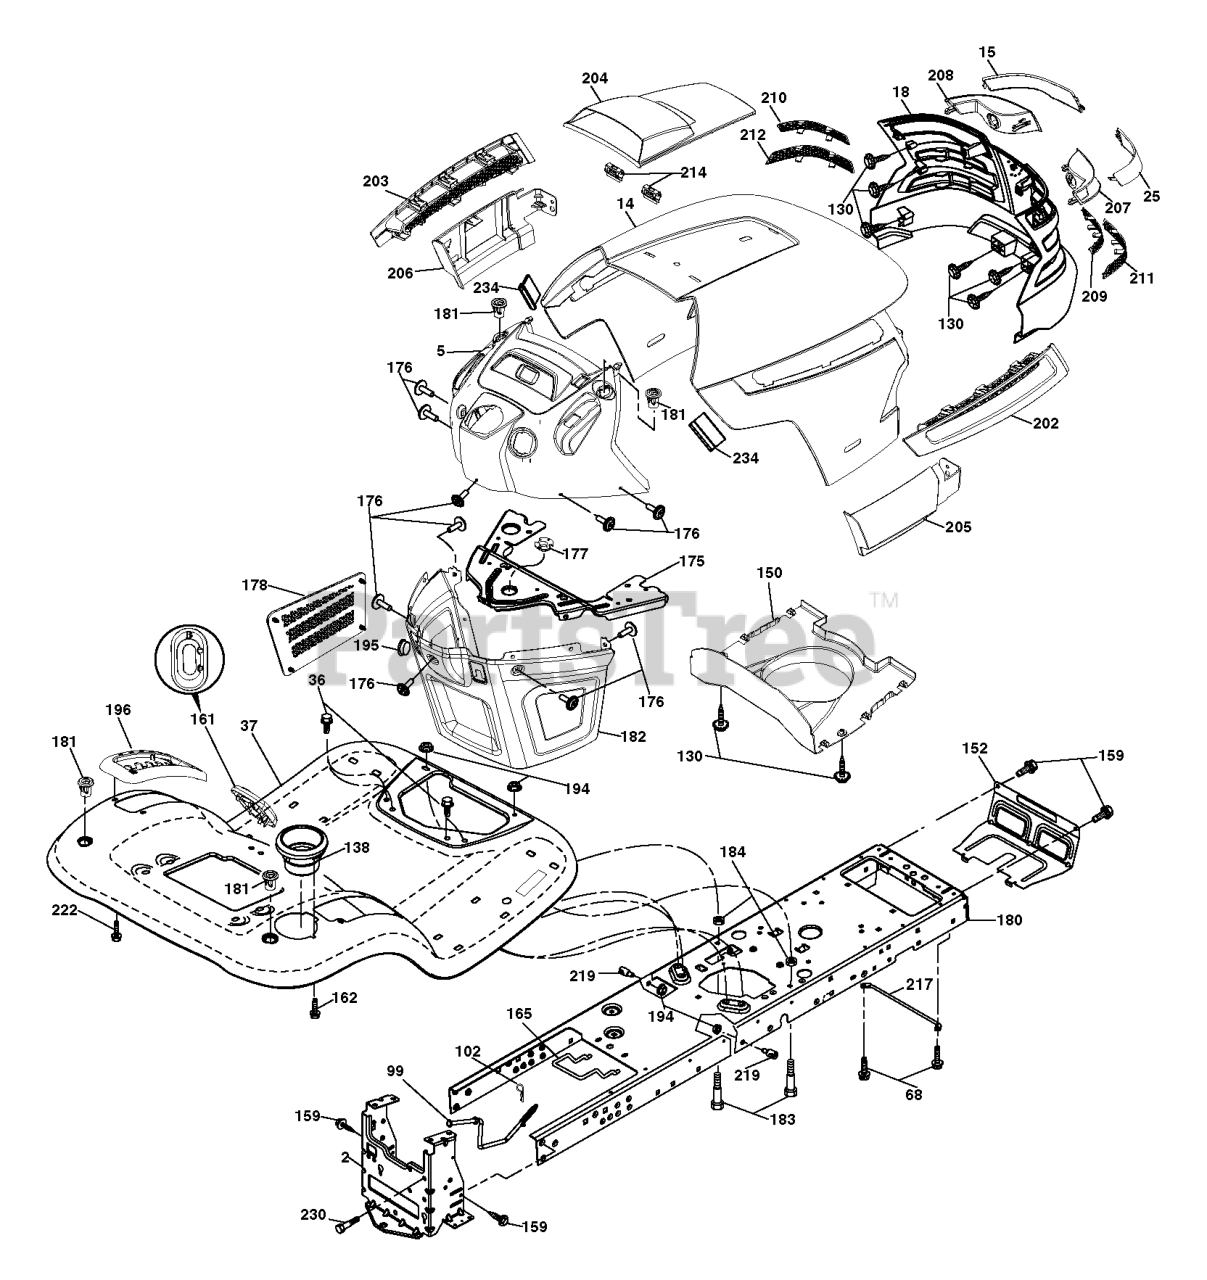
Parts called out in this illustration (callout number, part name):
2	DRAWBAR.1PC.NSTL
5	DASH.HUSQ.UPR.ELE.SVMD
14	HOOD.PNT.HUSQVARNA.GT.
15	LENS.LH.TEX.GT.HUSQ.CL
18	GRILLE.ASM.TX.GT.HUSQ
25	LENS.RH.TEX.GT.HUSQ.CL
36	SCREW 5/16"
68	Screw Thdrol 5/16-18 x 1/2
99	ROD ASM BYPASS
102	RETAINER M
130	SCREW
138	CUPHOLDER.TL.TEX.418
150	AIR.DUCT.TEXGT.HUSQ.SV
152	SHIELD.BROWNING/DEBRIS
159	SCREW, 3/8-16X3/4
161	RP WINDOW.FUEL.LT.TEX.GREY
162	SCREW.HI-LO.CONSOLE
165	SUPPORT.TANK.REAR.WIRE
175	PLATE.CROSSMEMBER.HUSQ
176	SCREW.#10-24X5/8.RN.QU
177	BUSHING, STEERING
178	CARGO.ASM.NET.TXGT.W/C
180	CHASSIS.STAMPING.LT/GT
181	BUSHING.MNT.FEND.CRGO.
182	DASH.LOWER.COMMON.12V.
183	BOLT.5/16-18X1-1/4 FULL.THREAD
184	SPACER.FENDER
194	NUT LOCK HEX FLANGE 5/16-18
195	PLUG.HOLE.DASH.LOWER.12V.BLK
196	CONSOLE.ASM.DECK.LIFT.
202	VENT.SIDE.HOOD.HUSQ.RH.GREY
203	VENT.SIDE.HOOD.HUSQ.LH.GRAY
204	VENT.TOP.HOOD.HUSQVARN
205	SKIRT.HOOD.SIDE.HUSQ.RH.GREY
206	SKIRT.HOOD.SIDE.HUSQ.LH.GREY
207	BEZEL.RH.TEX.GT.HUSQ
208	BEZEL.LH.TEX.GT.HUSQ
209	INSERT.HEX.GRILL.HUSQ.GREY
210	INSERT.HEX.GRILL.HUSQ.
211	INSERT.HEX.GRILL.HUSQ.
212	INSERT.HEX.GRILL.HUSQ.
214	CLIP.RETAINER.TINNER.
217	ROD PIVOT CHASSIS/HOOD
219	STUD.FASTNER.W/ANTI-ROTATE
222	SCREW.1/4-20X5/8
230	SHOULDER BOLT 5/16-18TT
